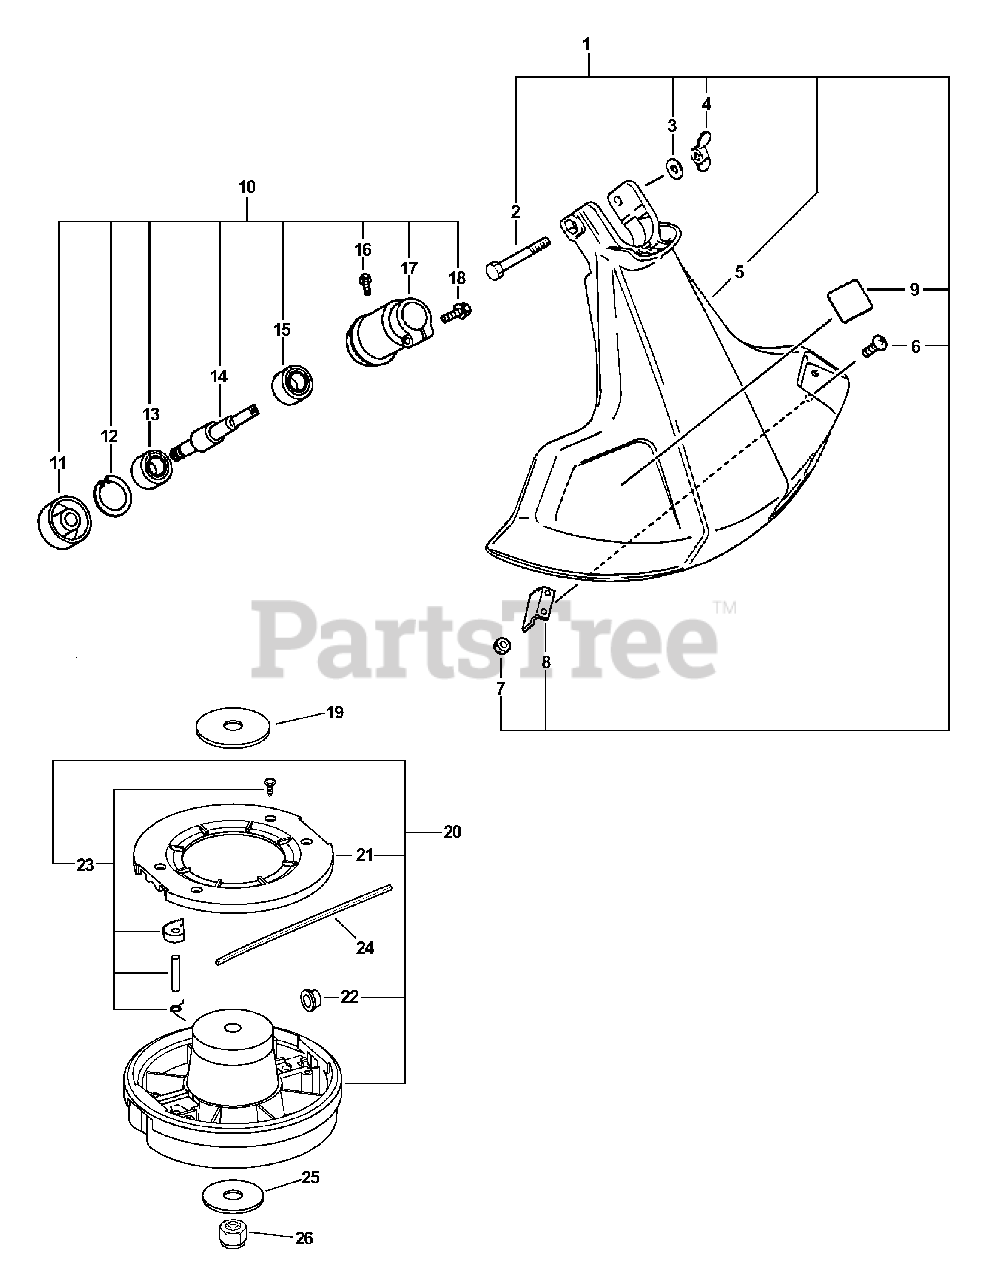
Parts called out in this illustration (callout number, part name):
1	SHIELD ASSY
2	BOLT 1/4"-20×2"
3	WASHER, 1/4"
4	NUT, WING 1/4"-20
5	SHIELD, DEBRIS
6	SCREW 5×16
7	NUT M5
8	CUTTER, LINE
9	LABEL, CAUTION
10	GEAR CASE ASSY
11	PLATE, ADAPTER - UPPER
12	E-RING 30
13	BEARING, BALL 6201
14	GEAR, SHAFT
15	BEARING, BALL 6200
16	SCREW 4×10
17	CASE, GEAR
18	BOLT - 5×25
20	TRIMMER HEAD, RAPID-LOADERT- 2 LINE
21	COVER, TOP
22	EYELET (PACKAGE OF 3)
23	PAWL KIT
24	LINE, CUTTING - 0.80" (20 PER PACKAGE)
25	WASHER 10
26	NUT, LOCK
